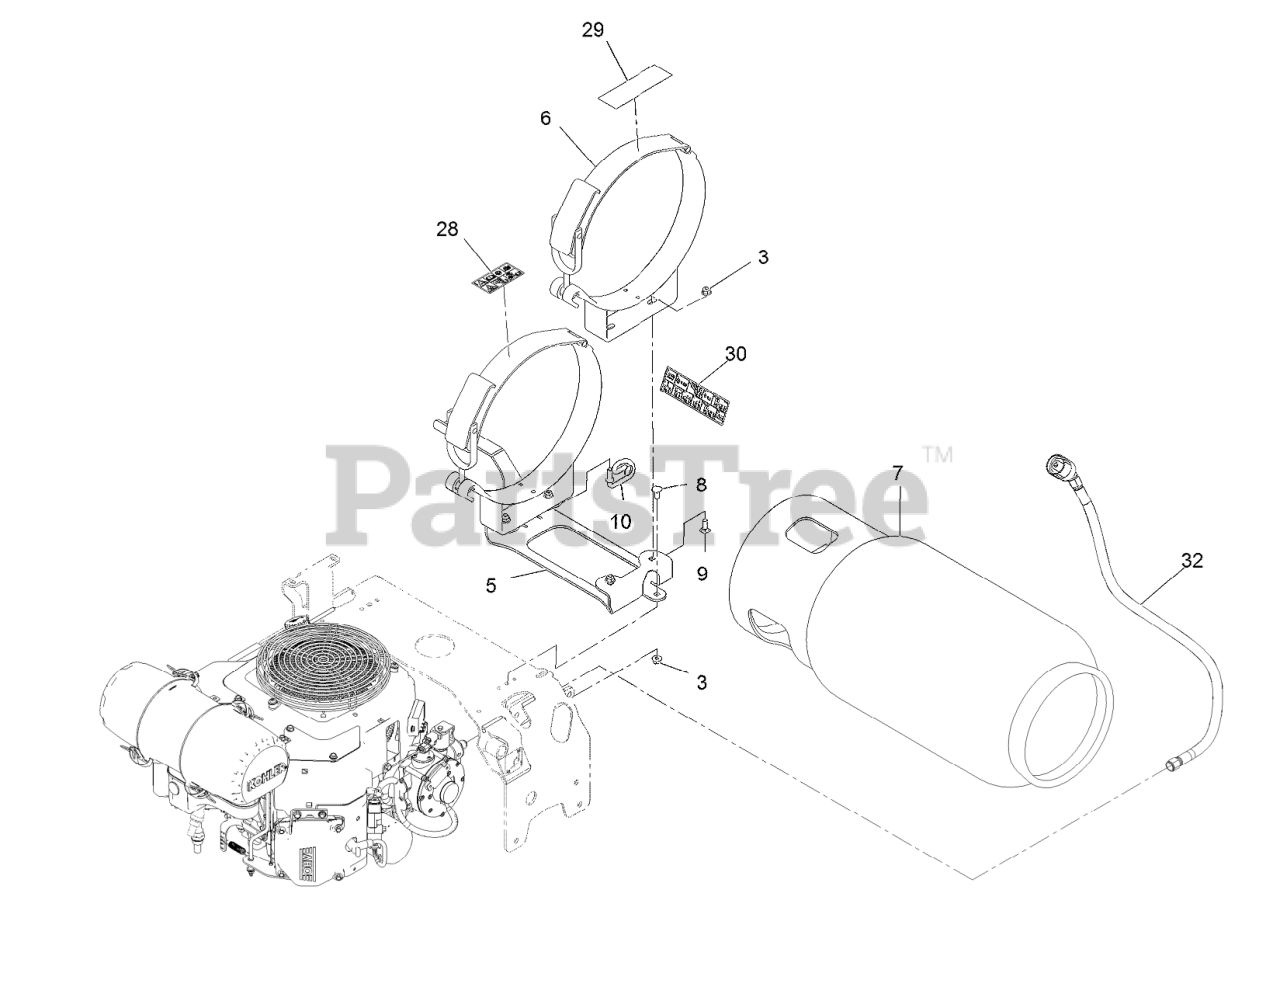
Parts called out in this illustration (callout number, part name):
3	NUT-HF, NI
5	WELD, TANK MOUNT
6	BRACKETS, LPG TANK - HORI
7	TANK, LP - 33.5 LB.HORIZO
8	SCREW-CARR
9	SCREW-CARR
10	RETAINER, LP HOSE
28	Decal-LPG Warning
29	Decal-LPG Horiz Tank Spec
30	Decal-LPG Fuel Tank Replacement
32	ASM, LPG HOSE W/CONNECTOR
